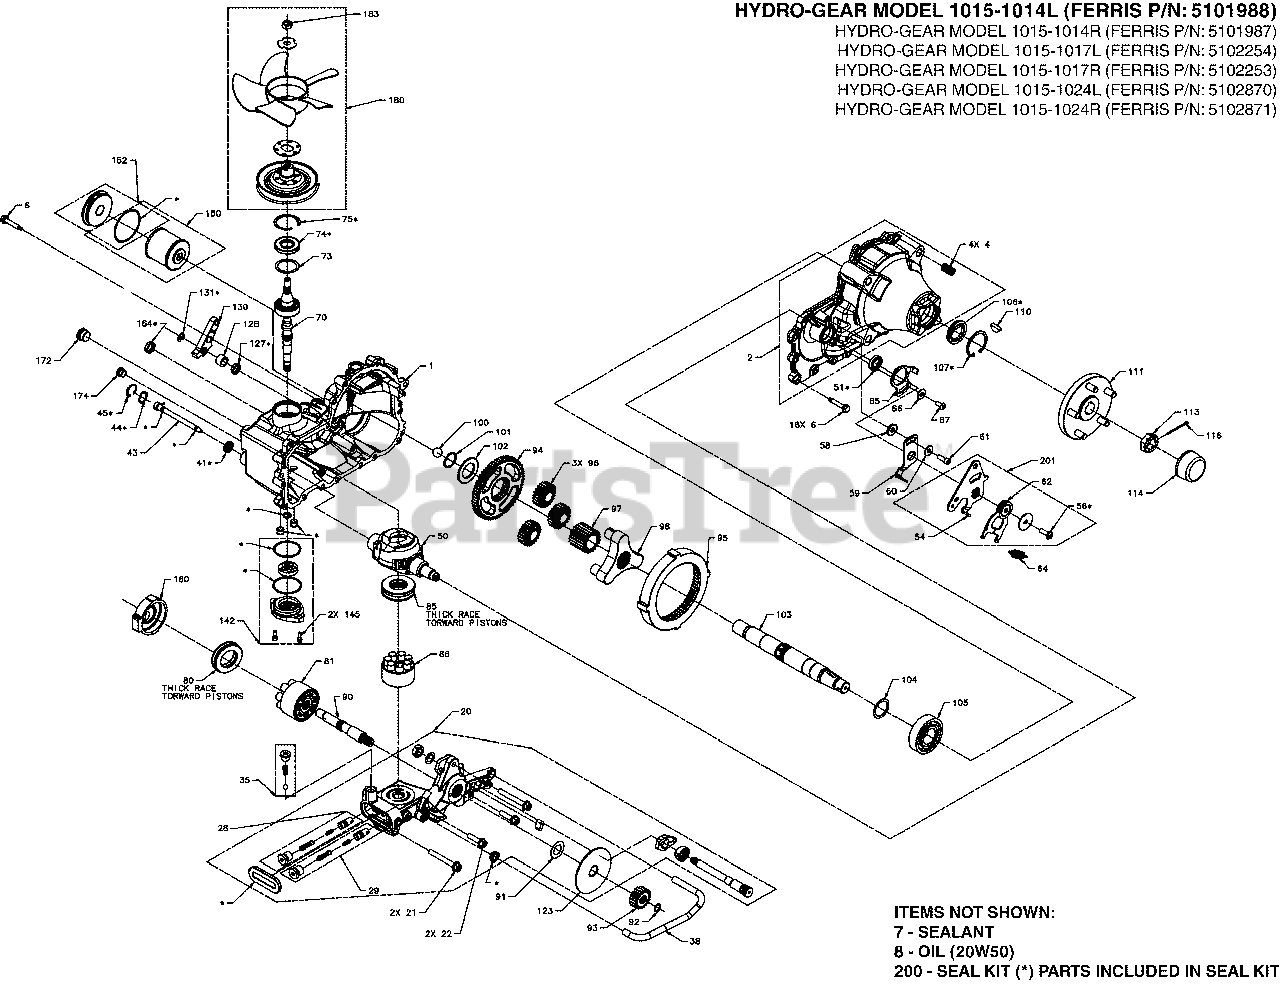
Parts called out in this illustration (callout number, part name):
114	Axle Cap (SV)
150	Kit, Filter (SV)
180	Kit, Fan/Pulley (SV)
200	Kit, Seal (SV)
